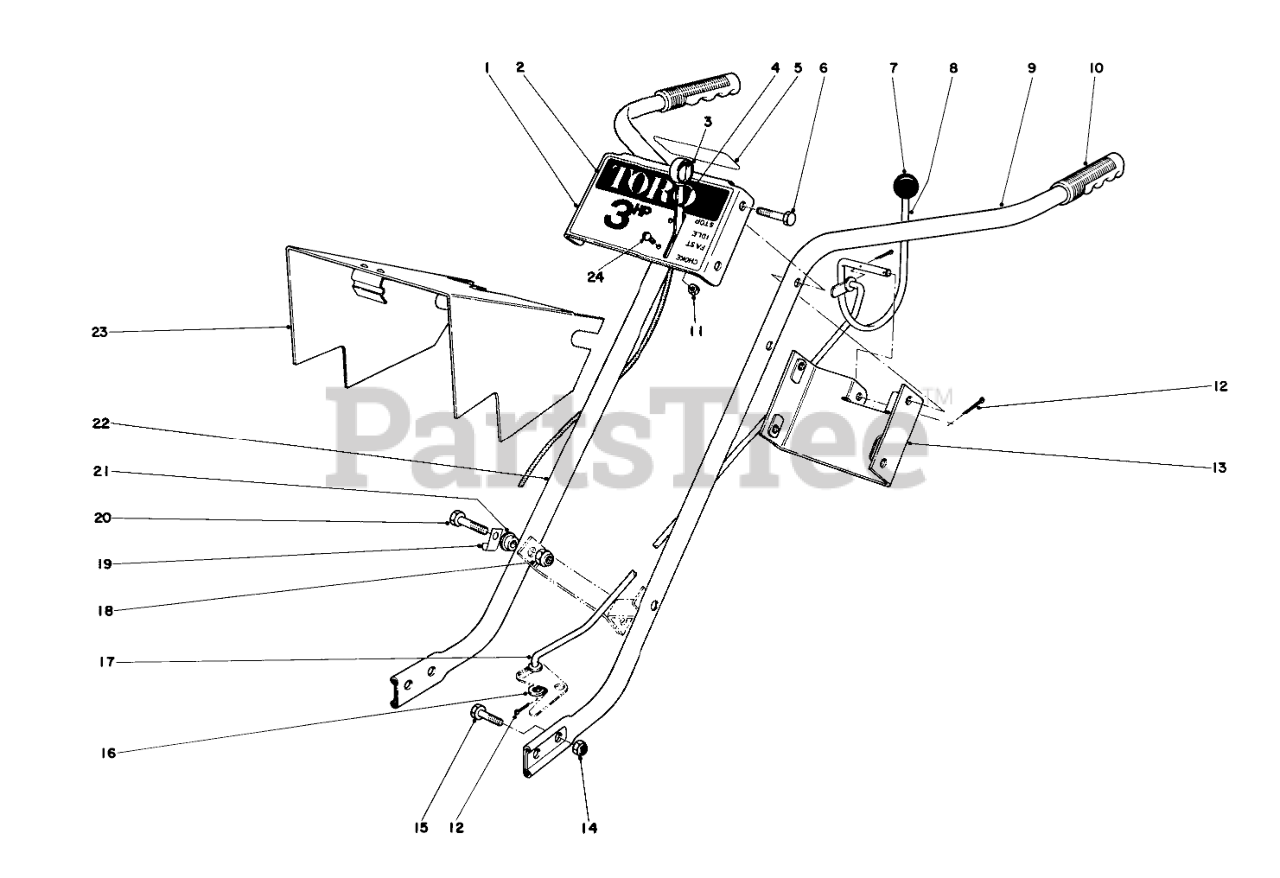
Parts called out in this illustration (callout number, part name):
1	Control Plate
2	Decal (Toro)
4	Throttle Control
5	Decal Clutch
6	SCREW-HH
7	KNOB-CONTROL
8	Clutch Control
9	Handle L.H.
10	Handle Grip
11	NUT-KEPS
12	PIN-COTTER
13	Handle Brace
14	NUT-LOCK, CONE
15	SCREW-HH
16	WASHER-FLAT
17	Clutch Rod
18	NUT-LOCK, CONE
20	SCREW-HH
21	Spacer
22	Handle R.H.
23	Pulley Cover
24	SCREW-PPH
